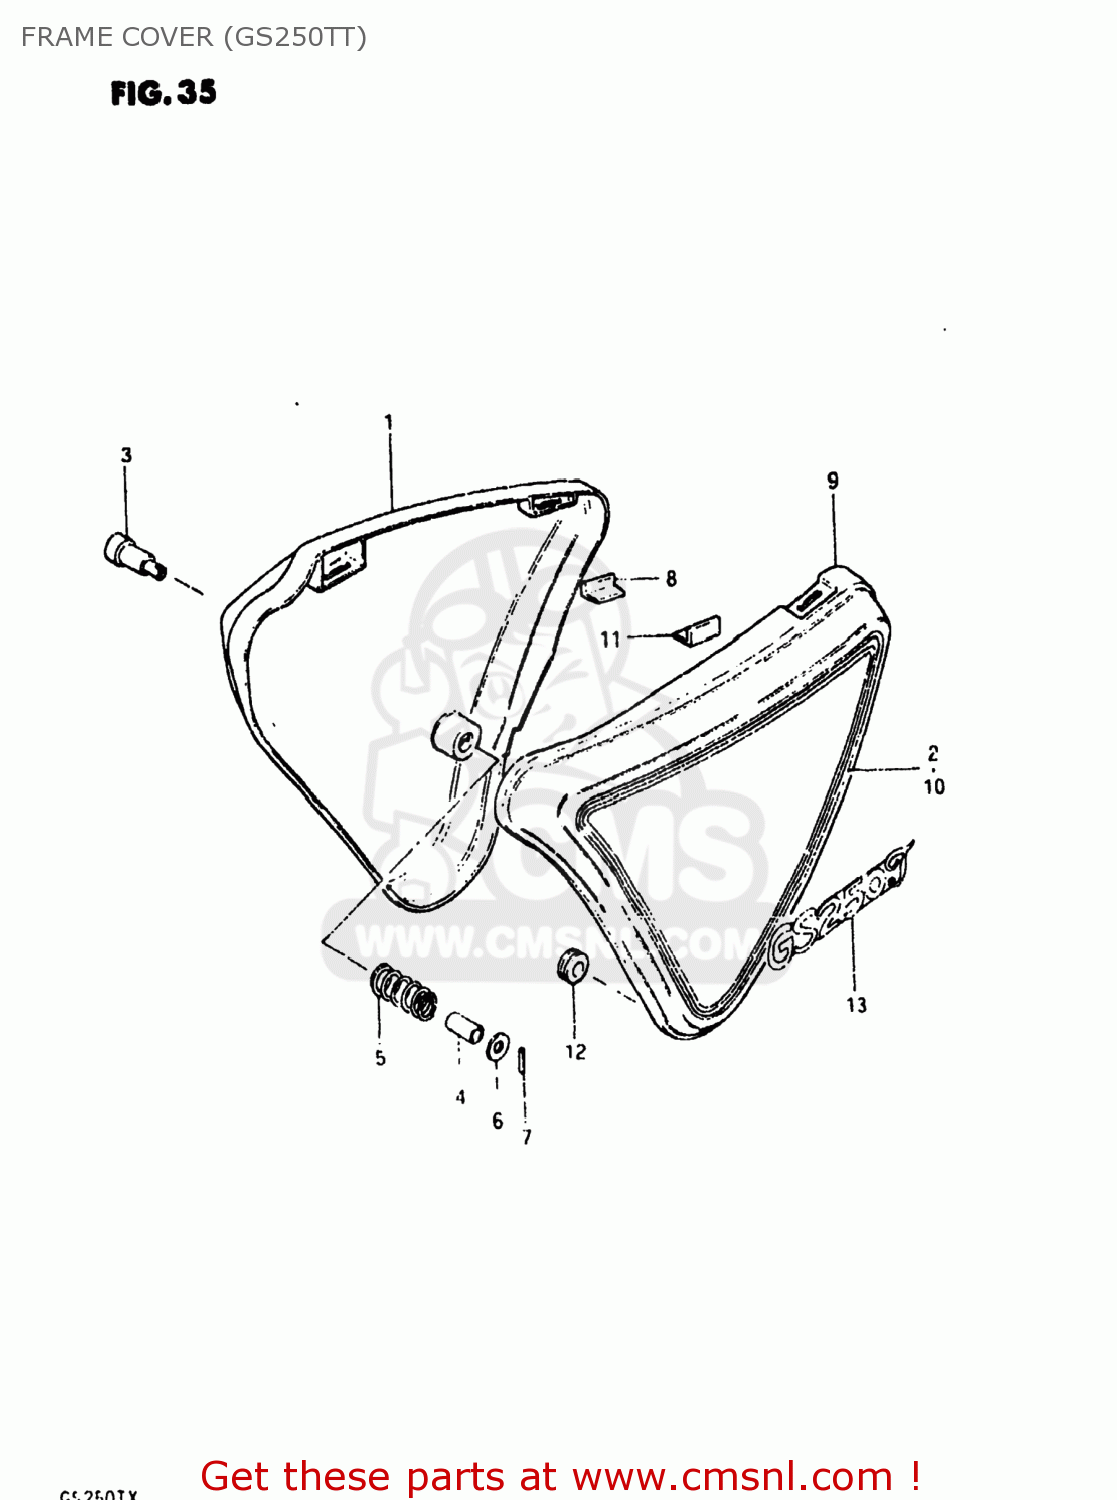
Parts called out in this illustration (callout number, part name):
1	COVER,FRAME,RIGHT
2	TAPE SET,FRAME COVER
3	KNOB,FRAME COVER,R
4	SPACER(14.9X17.3X13.5)
5	SPRING
6	WASHER (6.5X24X1.6)
7	PIN,SPRING(2.5X18)
8	CUSHION,FRAME COVER
9	COVER,FRAME,LEFT
10	TAPE SET,FRAME COVER
11	CUSHION,FRAME COVER
12	CUSHION
13	EMBLEM,FRAME COVER
